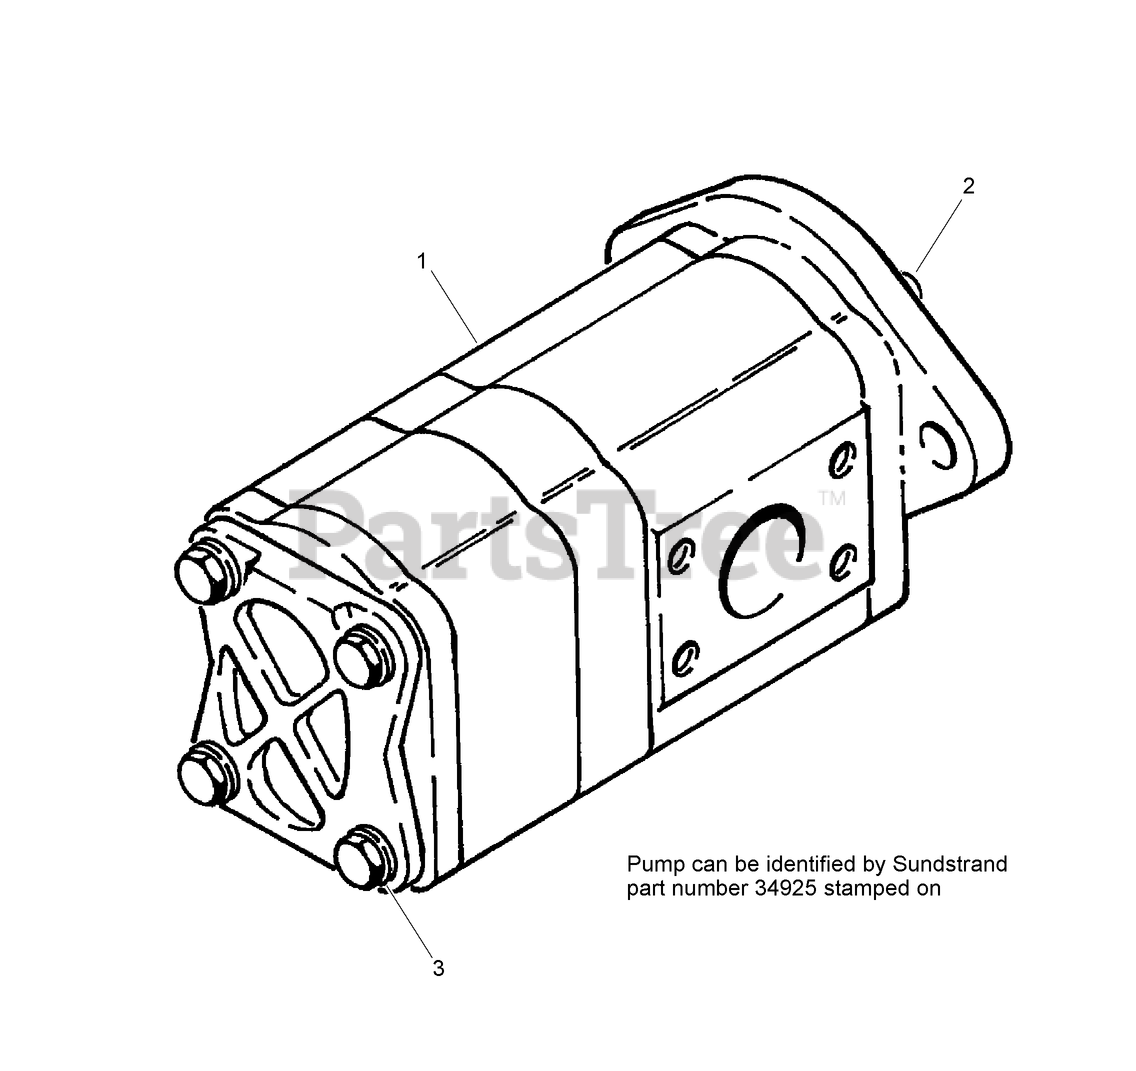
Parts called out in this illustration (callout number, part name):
1	PUMP ASSEMBLY - Dual
2	KIT - Dual Pump Seal Replacement (Includes all Seals and O-Rings)
3	BOLT - Special, Includes Washer
